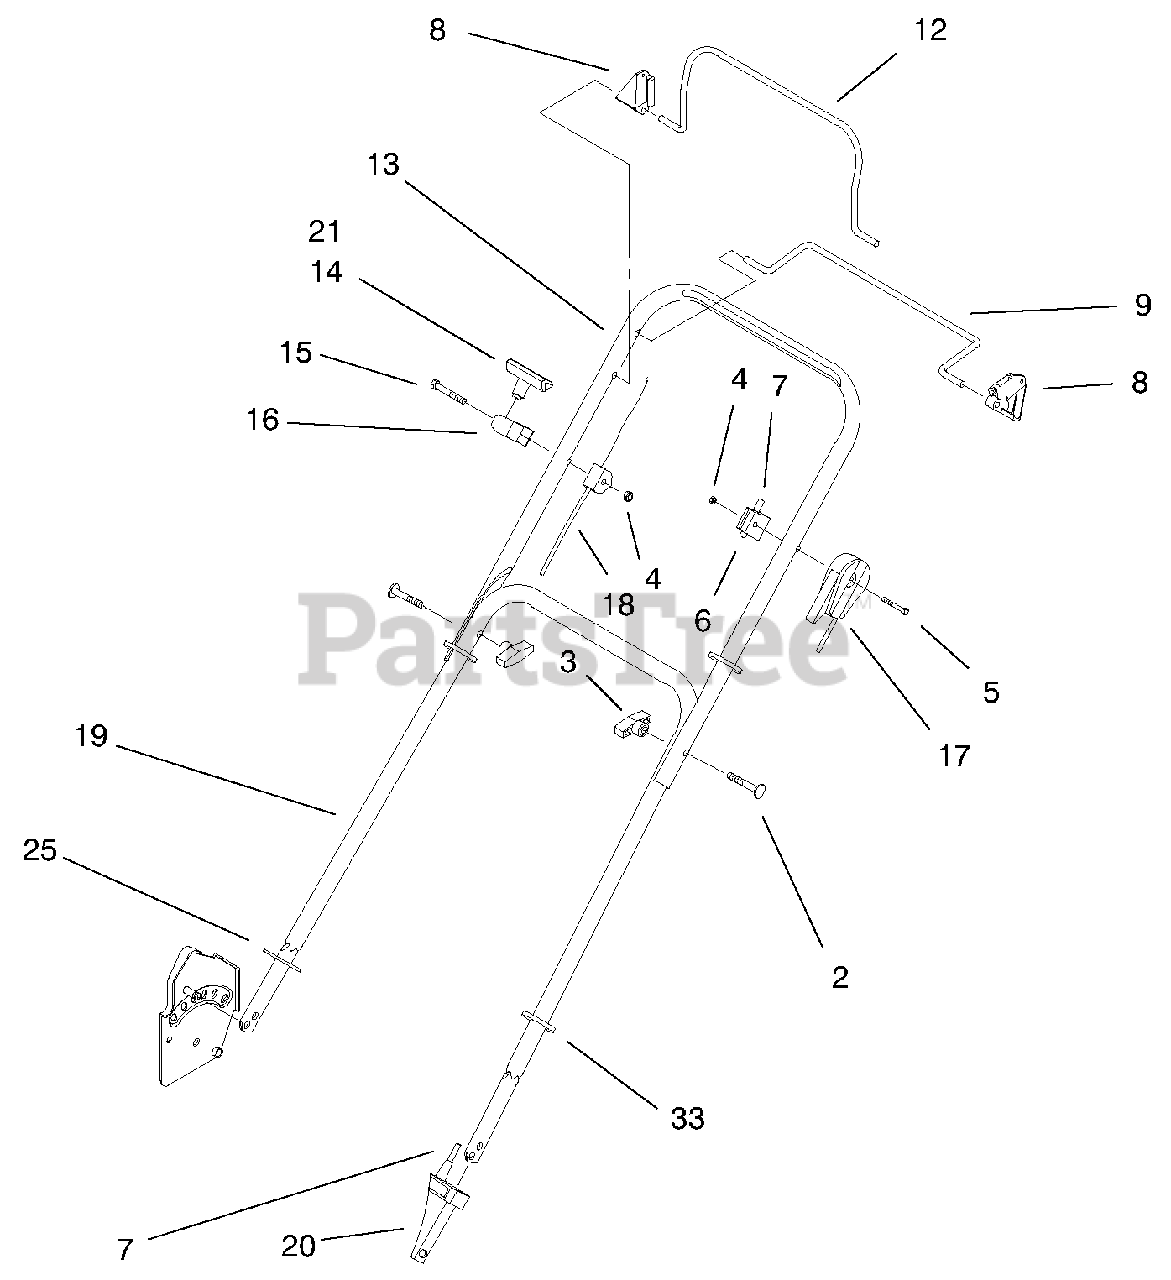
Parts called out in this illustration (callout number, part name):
2	Screw-Handle
4	Nut-Lock
5	Screw-HH
6	Anchor-Cable
7	Cable-Traction
8	Stop-Pivot
9	Bail-Sp Control
12	Bail-Flywheel Brake
13	Handle Section-Upper
14	Handle-Starter
16	Guide-Rope
17	Cable-Throttle 2 Cycle
18	Cable-Flywheel Brake
19	Handle Section-Lower
20	Anchor-Cable
21	Clip-Rope
31	Handle-Guard
33	Tie Strap
